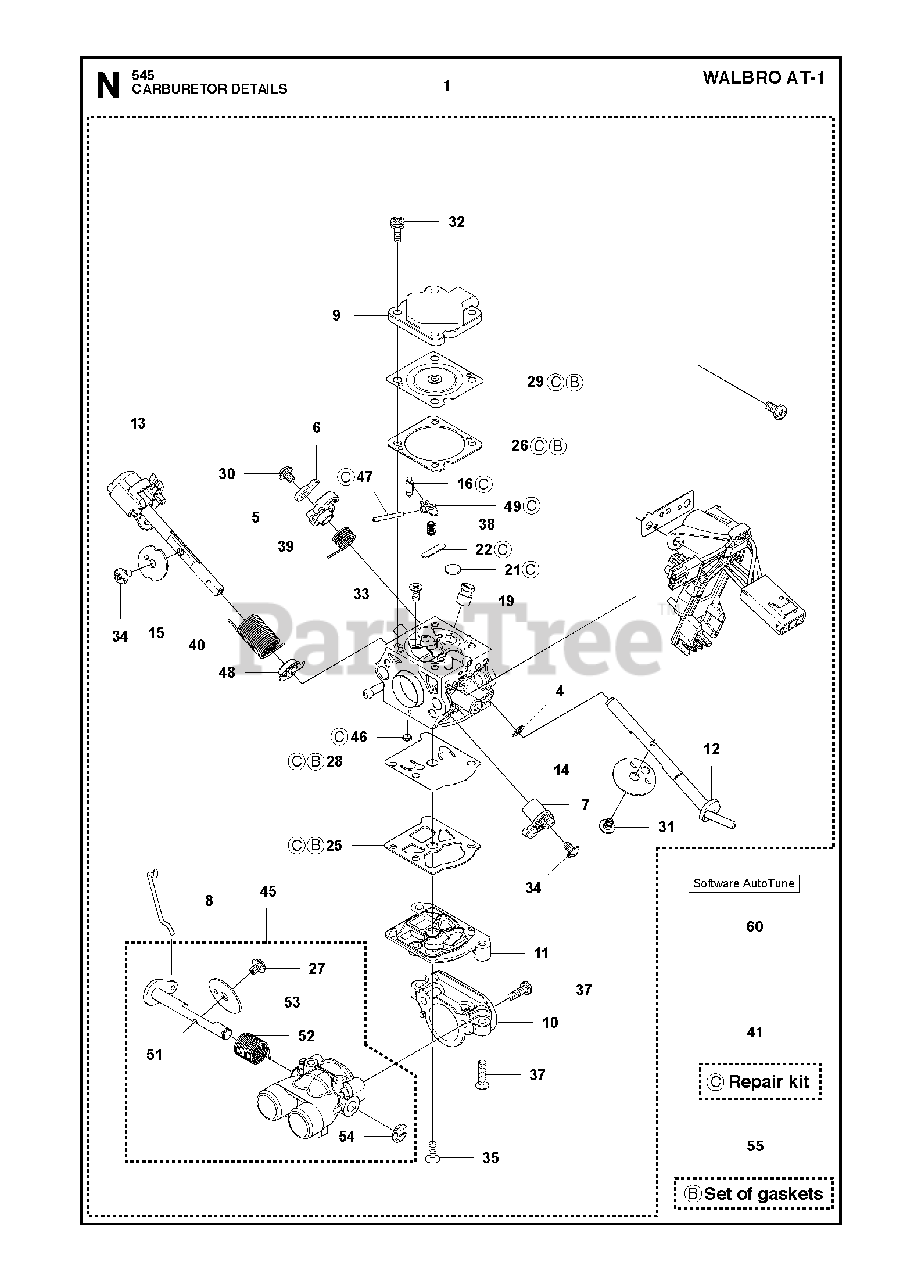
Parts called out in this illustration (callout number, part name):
1	RP CARBURETTOR
4	RETAINER
5	LEVER
6	LEVER
7	THROTTLE LEVER ASSY
8	LINK
9	COVER
10	INLET
11	COVER
12	SHAFT ASSY
13	SHAFT
14	VALVE
15	VALVE THROTTLE
16	INLET NEEDLE
19	NOZZLE ASSY
21	PLUG WELCH
22	PLUG
25	GASKET
26	GASKET
27	GASKET
28	DIAPHRAGM
29	DIAPHRAGM ASSY
30	SCREW
31	SCREW
32	SCREW
33	SCREW
34	SCREW
35	SCREW
37	SCREW
38	SPRING
39	SPRING
40	SPRING
41	REPAIR KIT
45	THROTTLE VALVE ASSY
46	FUEL INLET SCREEN
47	FULCRUM PIN
48	BUSHING
49	LEVER
51	SHAFT ASSY
52	SPRING
53	VALVE
54	E CLIP
55	GASKET KIT
60	Husqvarna TBD
